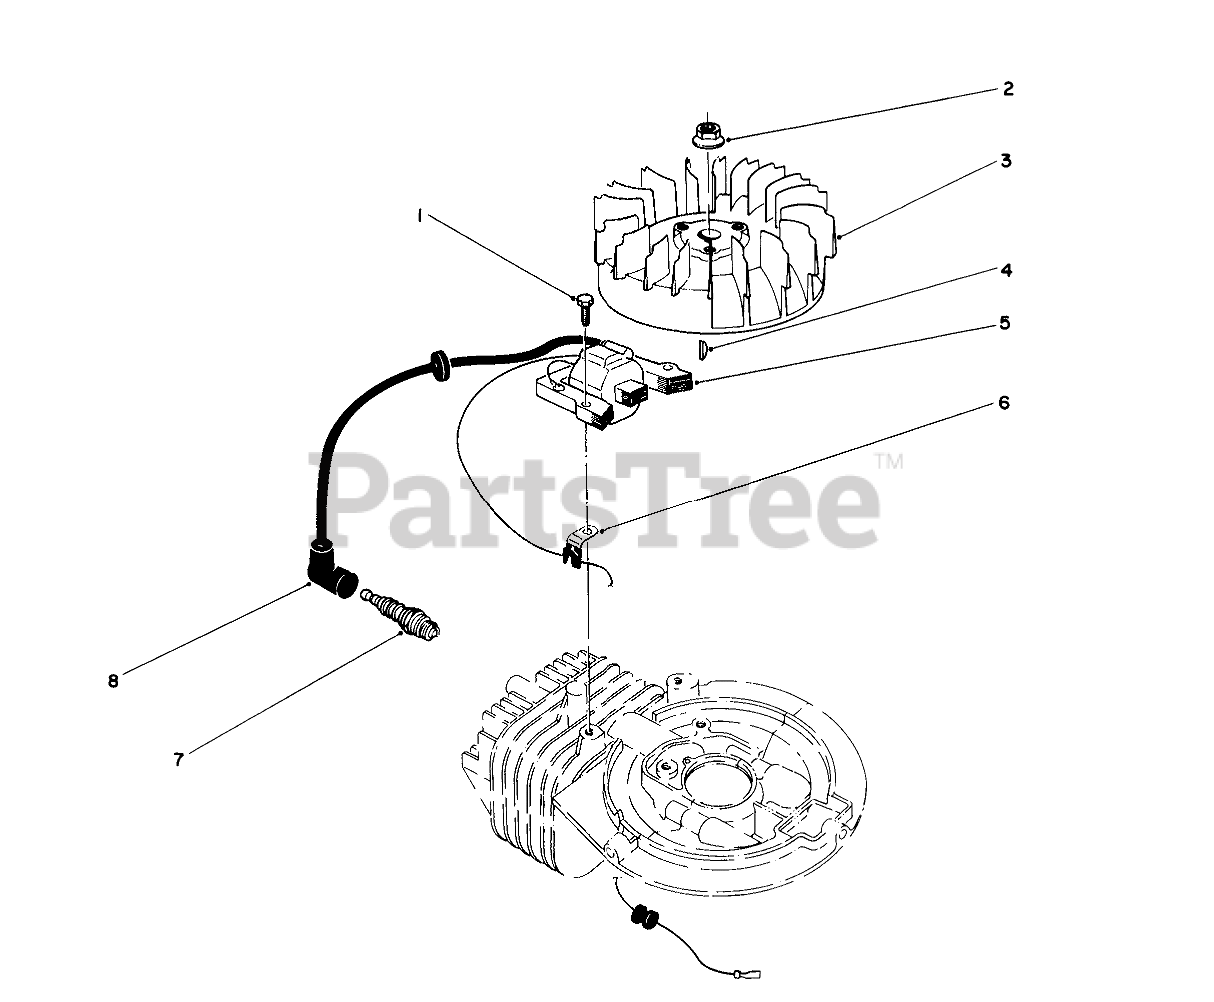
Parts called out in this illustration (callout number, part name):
1	SCREW
2	110 Nut
3	FLYWHEEL
5	COIL-MAGNETO
6	CLAMP
7	Sparkplug
8	CAP-SPARKPLUG
